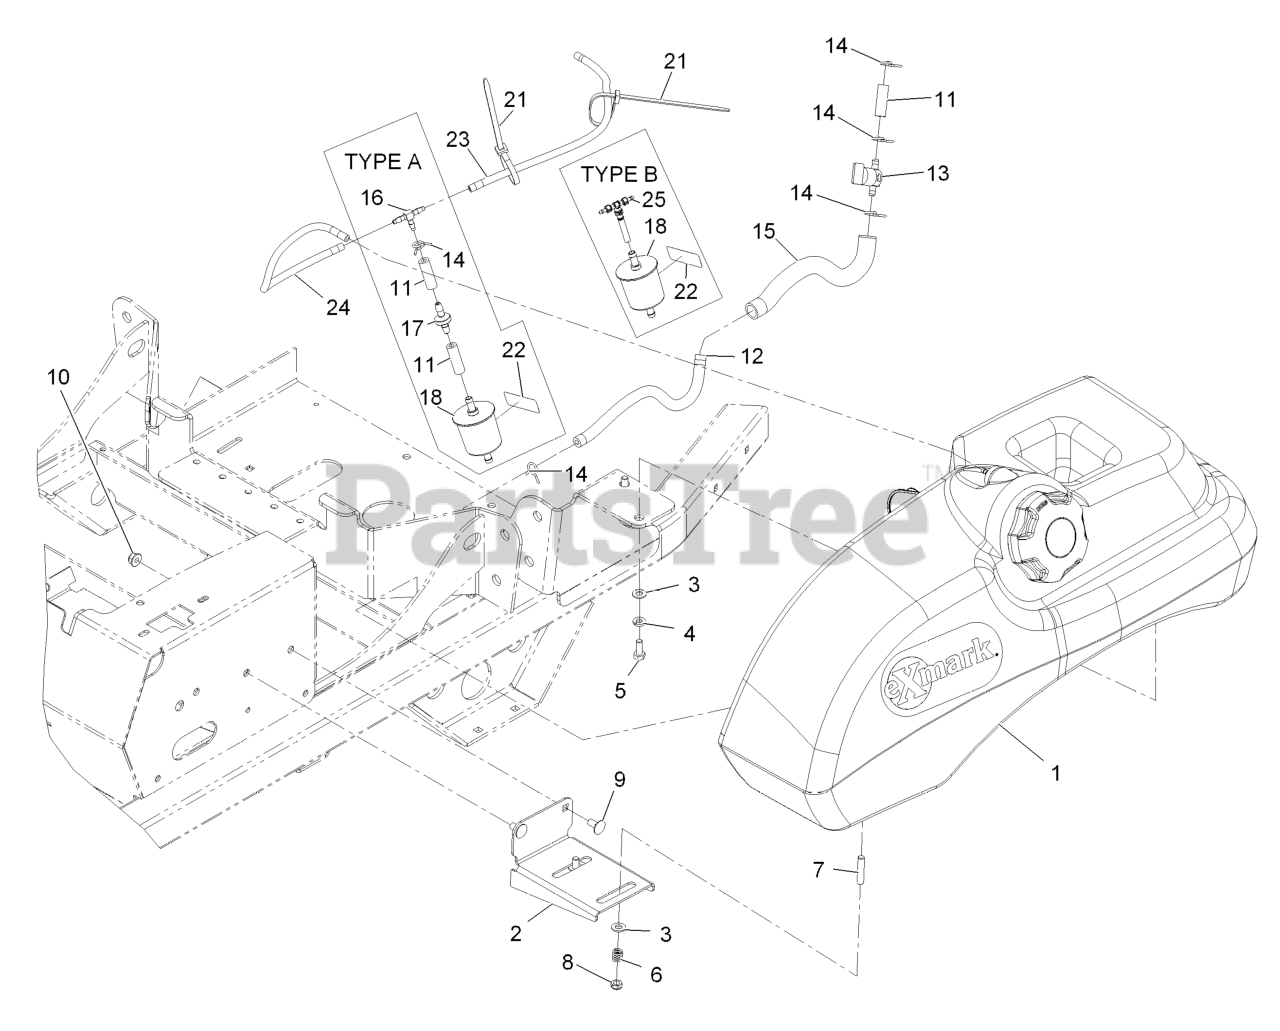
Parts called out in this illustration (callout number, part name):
1	ASM-FUEL TANK
2	BRACKET-TANK AND FENDER
3	WASHER-PLAIN
4	WASHER-LOCK
5	SCREW-HH
6	SPRING-TANK, FUEL
8	NUT-LOCK, NI
9	SCREW-CARR
10	NUT-HF, NI
11	HOSE-FUEL
12	HOSE-FUEL
13	VALVE-FUEL
15	CONDUIT-FUEL LINE
16	FITTING-TEE
17	VALVE-CHECK, FUEL
18	FILTER-FUEL
21	TIE-PLASTIC
22	DECAL-FILTER, EMISSIONS
23	HOSE,EMISSIONS
24	HOSE-EMISSIONS
25	TEE AND CHECK
